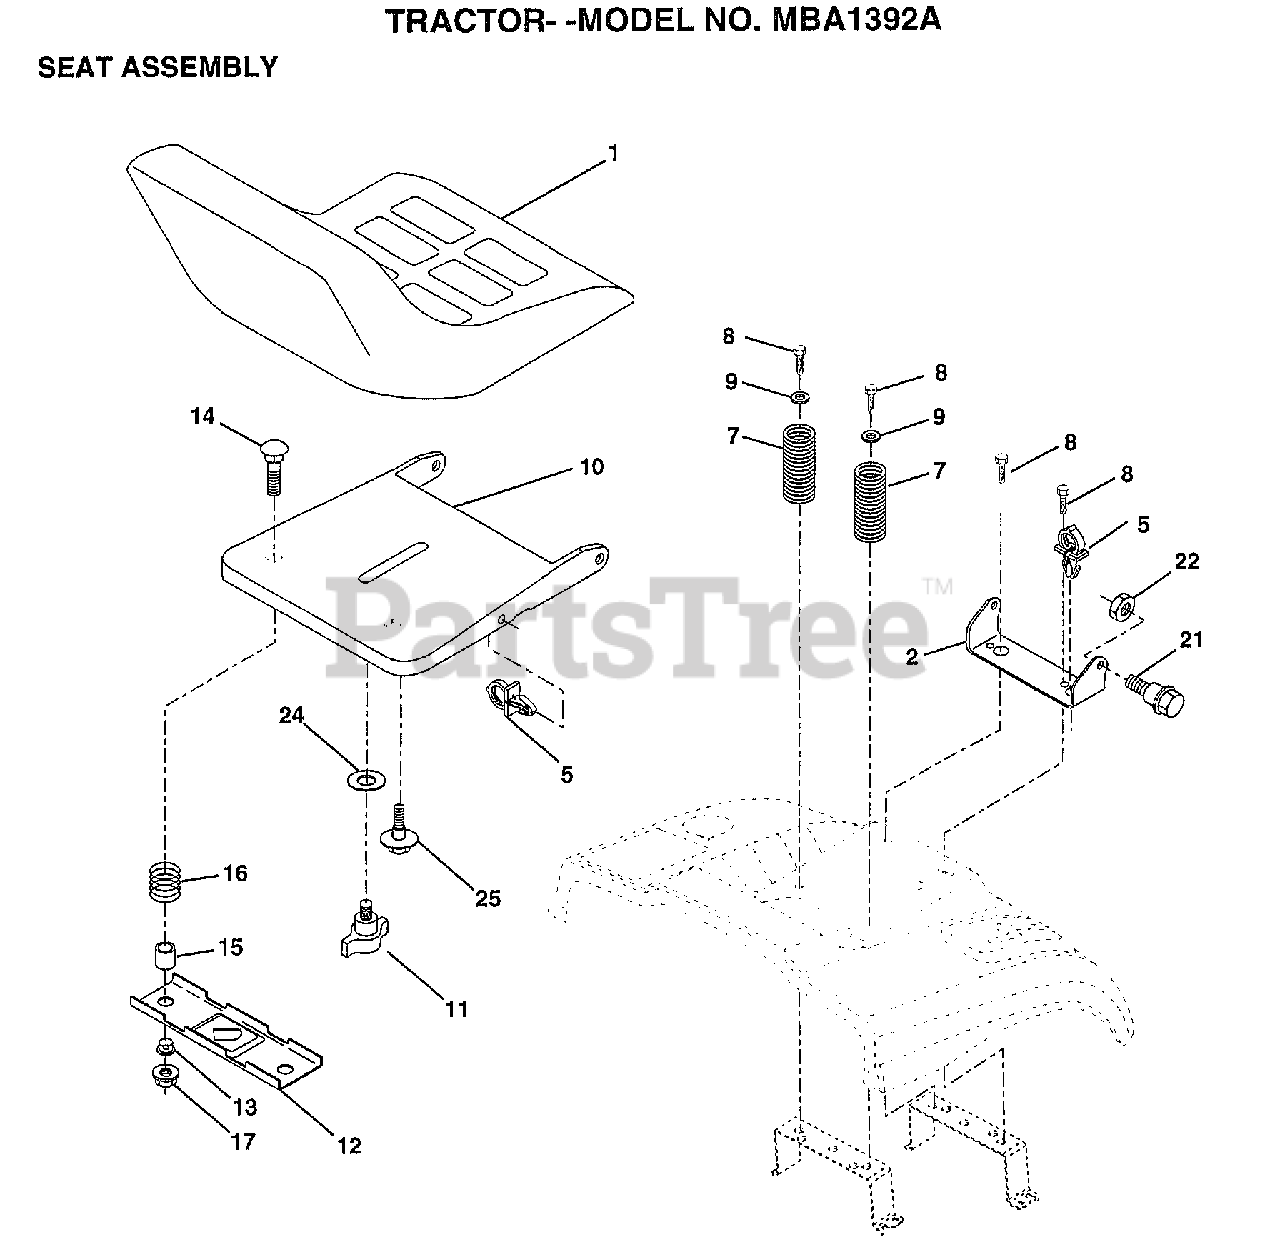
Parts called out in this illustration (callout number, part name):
1	SEAT.2400/1416.BK
2	BRACKET PVT SEAT
5	CLIP.PUSH-IN.HING
7	SPRING COMPRESSIO
8	SCREW GTV
9	WASHER
10	PAN-SEAT
11	KNOB.SEAT.ADJ.WINGNUT
12	BRKT SWITCH
13	BUSHING
14	BOLT-RD HD SQ NK
15	SPLIT SPACER
16	SPRING
21	"BOLT,SHOULDER"
22	NUT
24	WASHER
25	"BOLT,SHOULDER"
